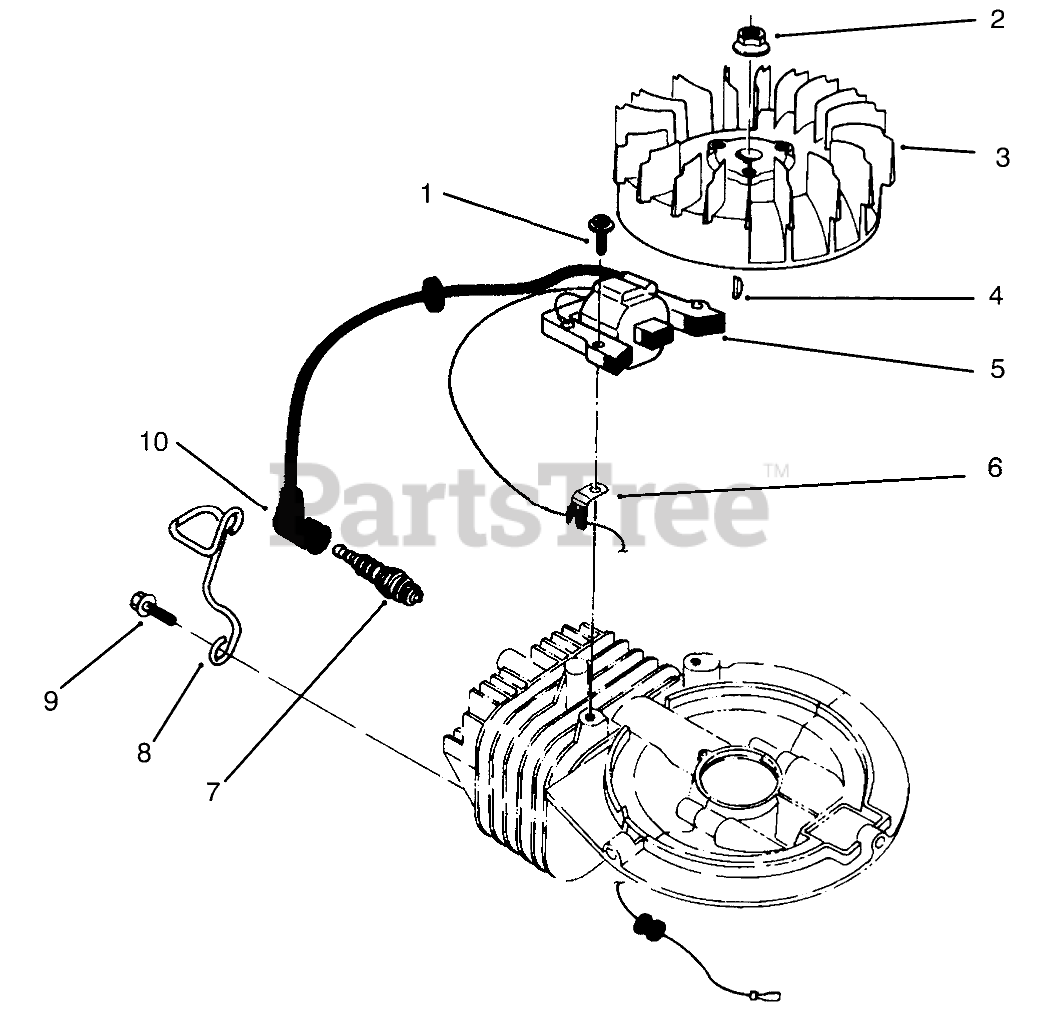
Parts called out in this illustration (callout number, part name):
1	SCREW
3	FLYWHEEL
5	COIL-MAGNETO
6	CLAMP
7	Sparkplug
8	PROTECTOR-PLUG
9	SCREW
10	CAP-SPARKPLUG
